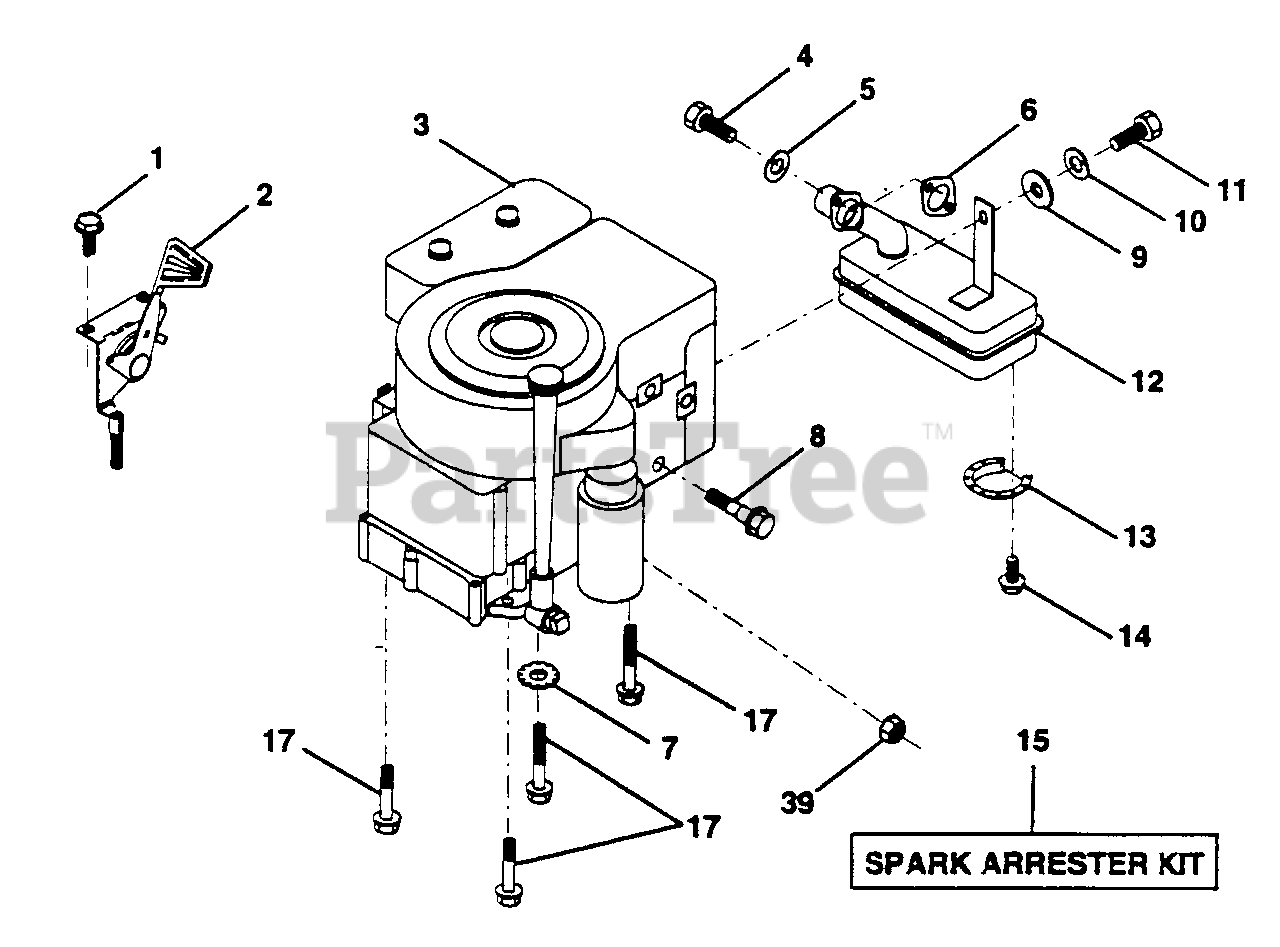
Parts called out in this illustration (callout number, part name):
1	Screw, Hex Thd. Cut 1/4-20 x 1/2 (AYP part number)
2	Control, Throttle (AYP part number)
3	Engine, Briggs and Stratton Model
4	Screw, Hex, Cap 5/16-18 x 3/4 (AYP part number)
5	Washer, Lock Heavy Helical Spring 5/16 (AYP part number)
6	Gasket, Exhaust (AYP part number)
7	Washer, Lock Ext. Tooth 3/8 (AYP part number)
8	Bolt, Shoulder 5/16 (AYP part number)
9	Washer 5/16 x 3/4 x 16 (AYP part number)
10	Washer, Lock Hvy Hlcl Spring 1/4 (AYP part number)
12	Muffler (AYP part number)
13	Deflector, Muffler (AYP part number)
14	Screw, Spiderloc Hex Hd ??8 x 1/2 (AYP part number)
15	Arrester, Spark (Optional equipment) (AYP part number)
17	Screw, Hex Washer Head. Thdrol. 3/8-16 x 1-1/2 (AYP part number)
39	Nut, Keps Hex 1/4-20 (AYP part number)
